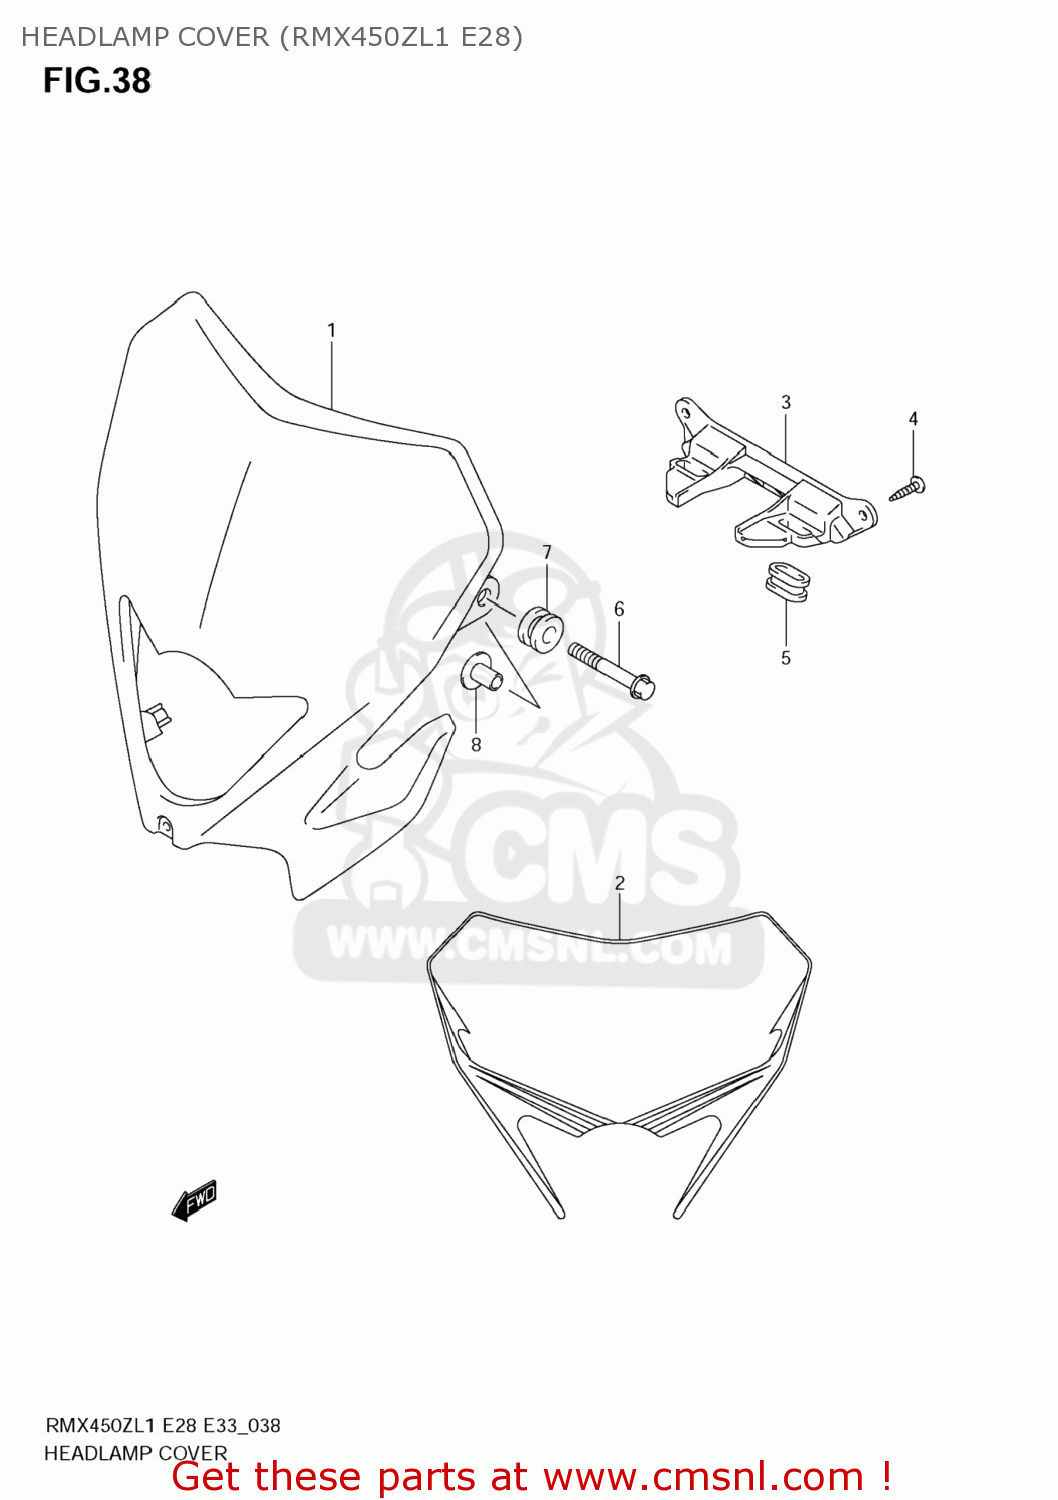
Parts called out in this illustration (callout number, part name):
1	COVER,HEADLAMP
2	TAPE,HEADLAMP COVER
3	COVER,HEADLAMP LWR
4	SCREW
5	CUSHION,HEADLAMP COVER
6	BOLT(6X25)
7	CUSHION
8	WASHER
